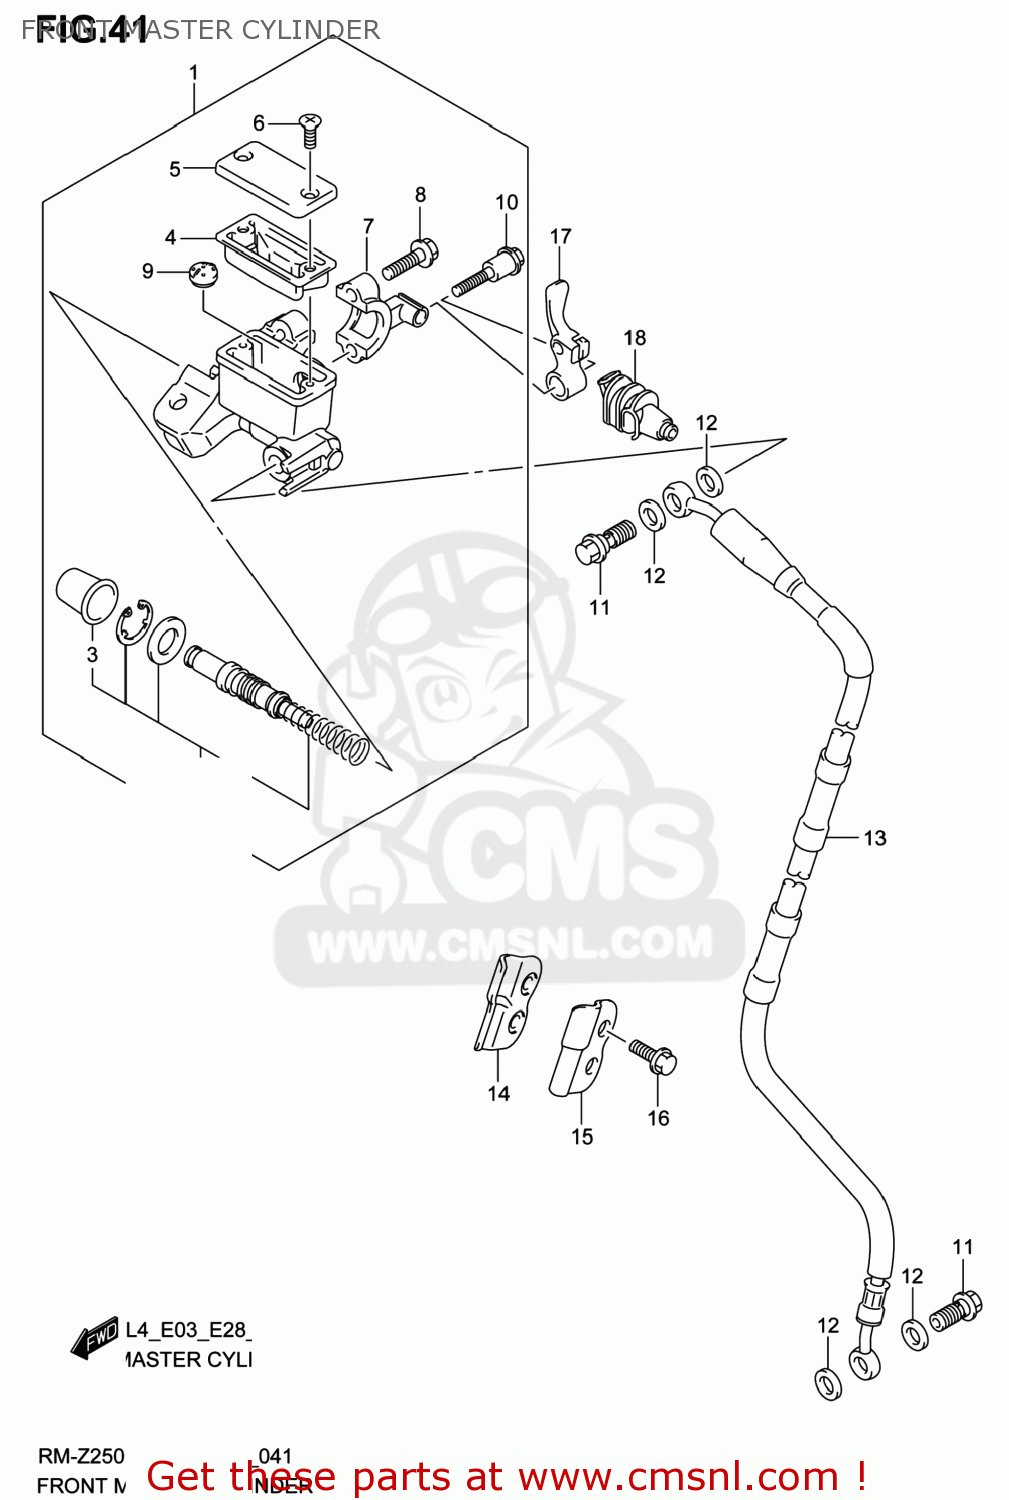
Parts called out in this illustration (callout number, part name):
1	CYLINDER ASSY,FR MASTER
2	PISTON & CUP SET
3	BOOT
4	DIAPHRAGM
5	CAP
6	SCREW
7	HOLDER
8	BOLT
9	SEPARATOR
10	BOLT,MASTER CYLINDER HOLDER
11	BOLT UNION
12	WASHER(10X15X1.5)
13	HOSE,FR BRAKE
14	CLAMP,FR BRAKE HOSE INNER
15	CLAMP,FR BRAKE HOSE
16	BOLT(6X16)
17	LEVER,MASTER CYLINDER HOLDER
18	COVER,MASTER CYL HOLDER LEVER
